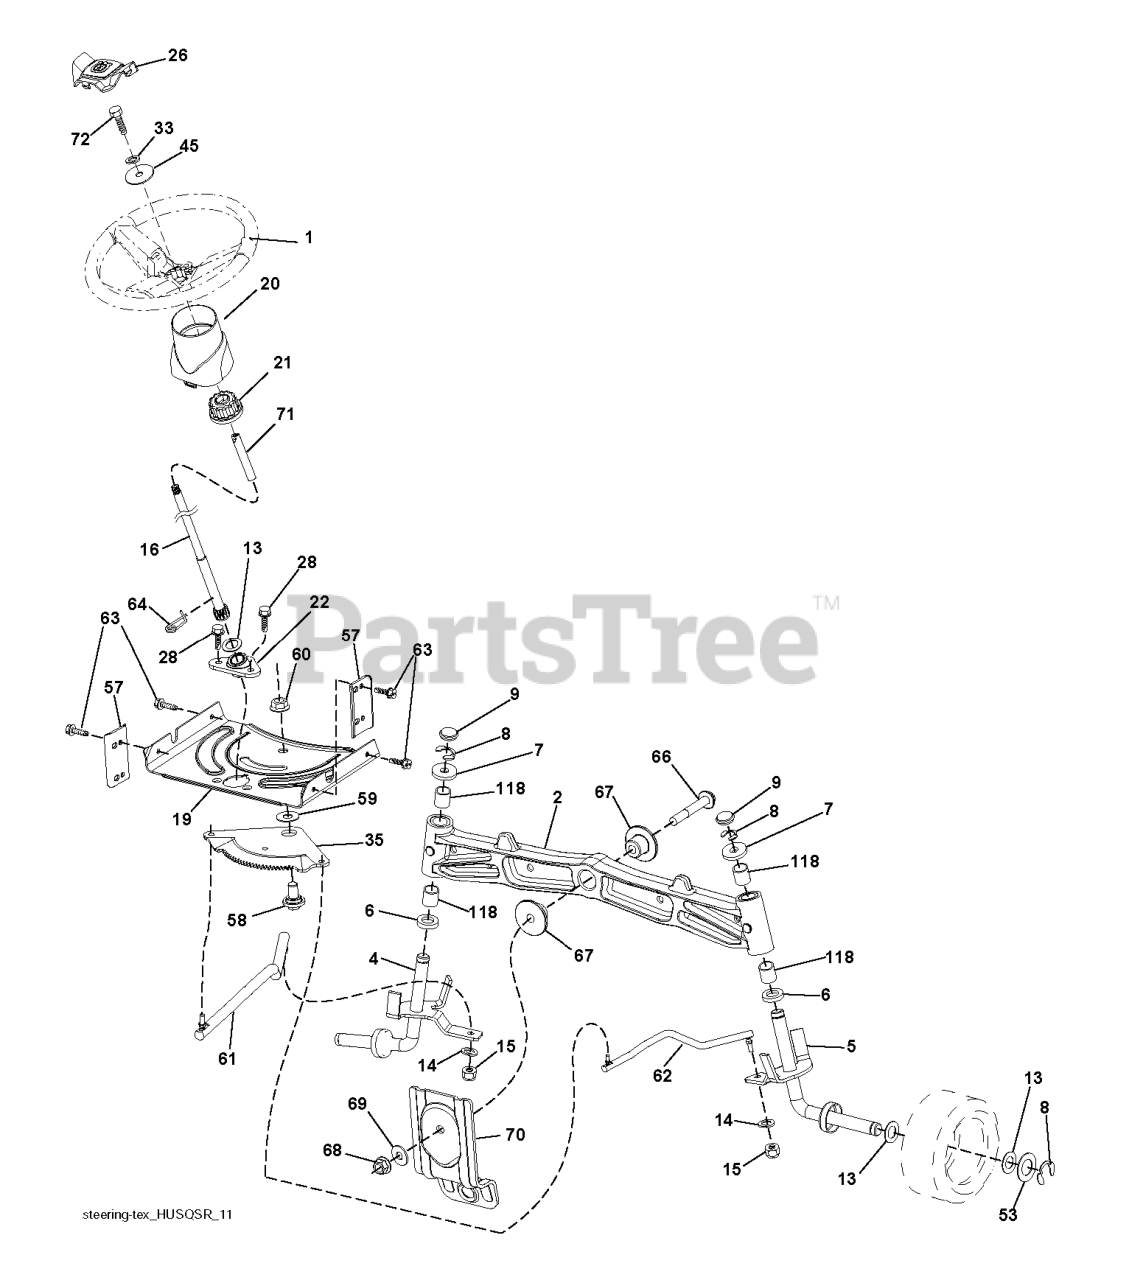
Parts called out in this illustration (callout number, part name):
1	RP WHEEL.STEER.HUSQ.PREM.OVMLD
2	AXLE.SVC.ASM CAST IRON.TEX
4	SPINDLE.WELDED.LH.15"TEX
5	SPINDLE.WELDED.RH.15"T
6	THRUST WASHER
9	CAP.SPINDLE.BLACK
14	WASHER, LOCK 3/8
15	NUT CROWNLOCK 3/8-24
16	SHAFT STEERING
19	PLATE.STEER.DDL.NLT/NG
20	BOOT, STEERING
21	ADAPTER, WHEEL STNG..
22	BUSHING.ASM.STEERING.A
26	RP INSERT.CAP.WHL.STRG.HUSQ.
28	SCREW, 3/8-16X3/4
33	WASHER.LOCK.HVY.HLCL.SPR.5/16
35	GEAR.SECTOR.PLATE.DDL.
45	WASHER.11/32
53	WASHER.HARDENED
57	BRACKET.UPSTOP.TEX
58	BOLT.SHOULDER.SECTOR.P
59	WASHER.THURST.SECTOR.S
60	NUT FLANGE LOCK 5/8-11
61	DRAGLINK.LH.BALLSTUD.D
62	DRAGLINK.RH.BALLSTUD.D
63	SCREW
64	RETAINER.CLIP.SPRING.S
66	BOLT HEX FGHD 7/16-14 X 3 SERR
67	BUSHING.PM.FRONT AXLE
68	NUT.LOCK.FLANGE.7/16
69	WASHER.1.5X.505X.118
70	BRKT.DECK.SUSPENSION.F
71	SHAFT EXTENSION STEERING
72	BOLT YT
79	DECAL.WHEEL.STRG.LGN.H
118	BUSHING, AXLE CAST
